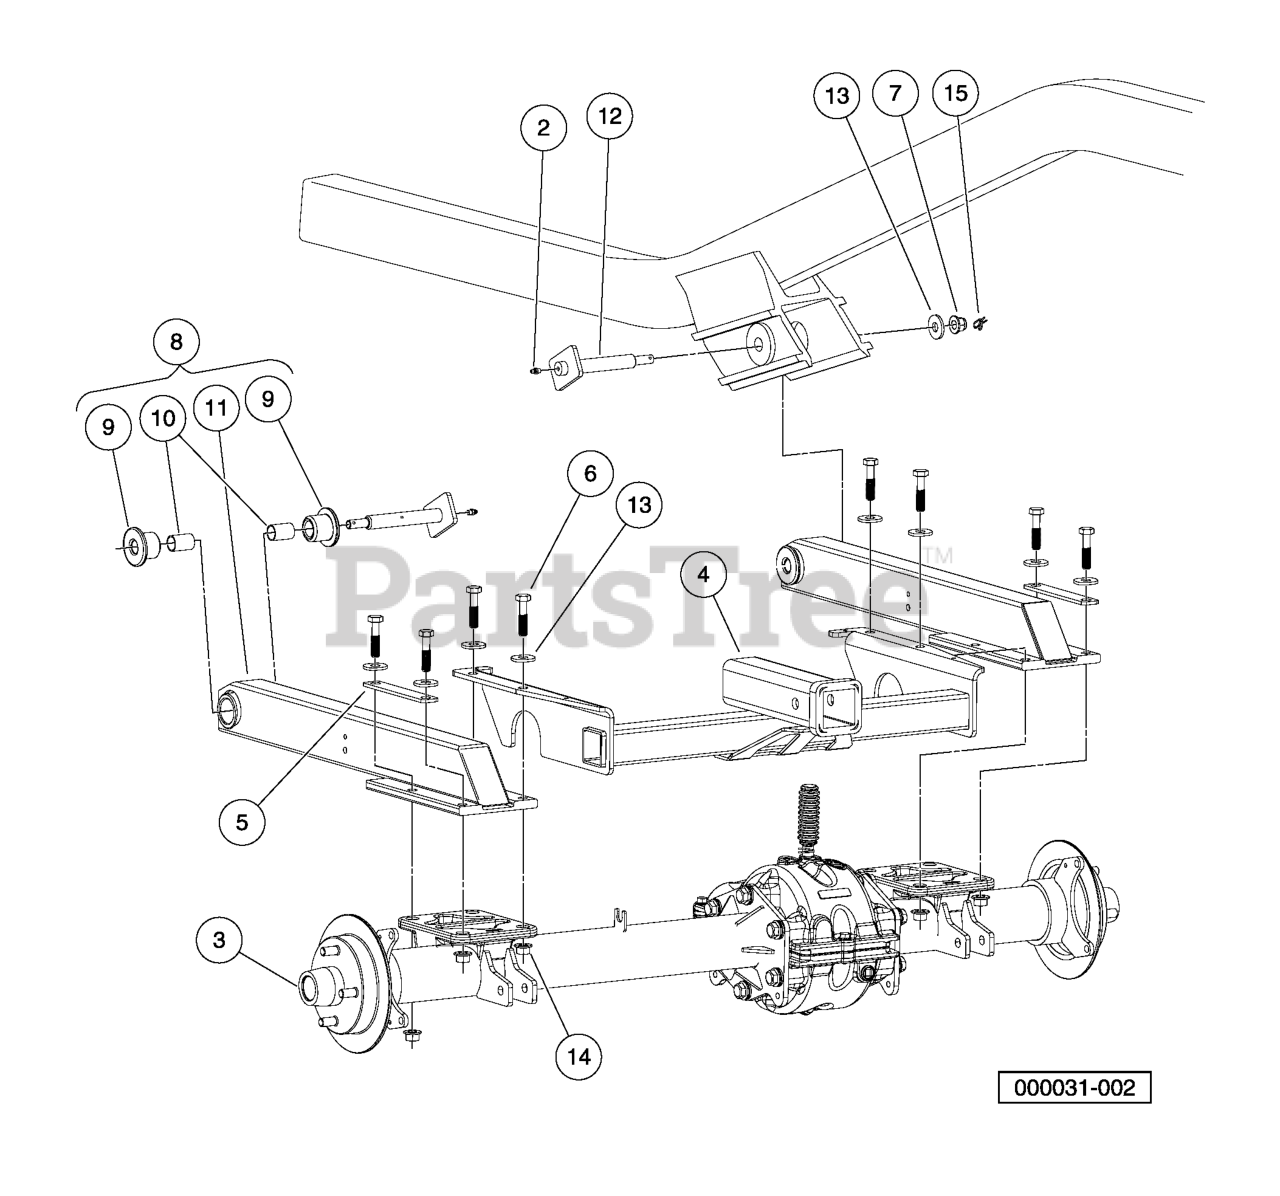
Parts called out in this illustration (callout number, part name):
1	Instl, Rear Suspension
2	FITTING, 1/4-28 THRD FRM GREAS
3	CENTER CAP, RUBBER
4	WELDMENT, RECEIVER, REAR
5	WASHER, STRIP, SWINGARM
6	BOLT FLG, M12X1.75X50
7	NUT FLG, M12X1.75, NYLON GR 10
8	Sub Asm Swingarm
9	BUSHING, PIVOT, URETHANE
10	BUSHING, TEFLON
11	SWINGARM, REAR, AWD
12	PIN, SWINGARM, WELDMENT
13	WASHER, M12 HARD REGULAR
15	COTTER-RUE RING
